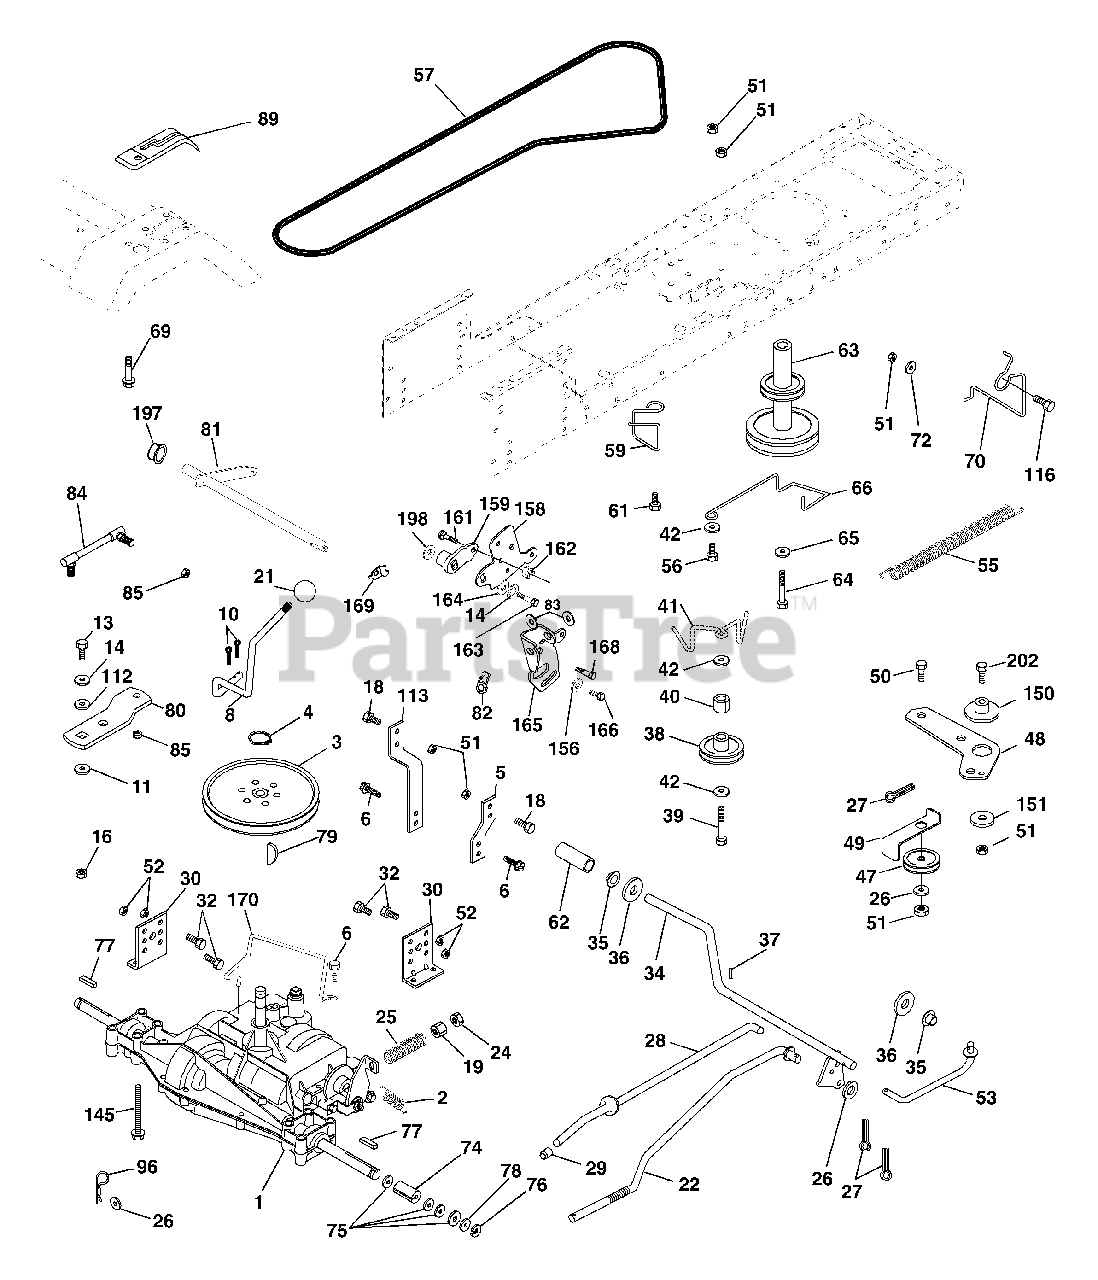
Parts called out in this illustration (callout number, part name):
2	Spring Return Brake T/a Zinc
3	Pulley Transaxle 18" tires
4	Ring Retainer # 5100-62
5	Strap Torque 30 Degrees
6	Screw 5/16-18 X 3/4
8	Rod Shift Fender Adjust Lt
10	Pin Cotter 1/8 X 1 Cad
11	Washer Plate Shf 388 Sq Hole
13	Bolt 1/4-28 Unf Gr 8 W/Patch
14	Washer Lock Hvy Helical
16	Nut Lock Hex w/ins 5/16-18
18	Bolt, Fin Hex 3/8-16 UNC x 1 Gr. 5
19	Nut Lock 3/8-16 Unc
21	Knob
22	Rod Brake Blk Zinc 26 840
24	Nut Hex Jam 3/8-16 Unc
25	Spring Rod Brake 2 00 Zinc
26	Washer 13/32 X 13/16 X 16 Ga
27	Pin Cotter 1/8 X 3/4 Cad
28	Rod Brake Parking LT/YT
29	Cap Brake Parking
30	Bracket Mtg Transaxle
32	Bolt Hex Hd 5/16-18unc X 3/4
34	Shaft Asm Pedal Foot
35	Bearing Nylon Blk 629 Id
36	Washer 21/32 X 1 X 16 Ga
37	Pin Roll 3/16 X 1"
38	Pulley Idler Flat
39	Bolt Fin Hex 3/8-16unc X 2-3/4
40	Spacer Split 395 X 59 Bzp
41	Keeper Belt Flat Idler
42	Washer 13/32 X 13/16 X 12 Ga
47	Pulley Idler V Groove Plastic
48	Bellcrank Asm
49	Retainer Belt Style Spring
50	Bolt Hex Hd 3/8-16unc X 1-1/2
51	Nut Crownlock 3/8-16 Unc
52	Nut Crownlock 5/16-18 Unc
53	Link Clutch
55	Spring Return Clutch 6 75
56	Bolt Fin Hx 3/8-16 X 1/4
57	V-Belt Ground Drive 95 25
59	Keeper Belt Span Ctr
61	Screw 3/8-16x.75
62	Cover Pedal Blk Round
63	Engine Pulley LT/YT
64	Bolt Hex
65	Washer Lock Hvy Hlcl Spr 7/16
66	Keeper Belt Engine Foolproof
69	Screw Hex wsh Hi Lo 1/4 x 1/2 unc
70	Guide Belt Mower Drive RH
72	Washer 13/32 X 1-1/4 X 12 Ga
74	Spacer Axle
75	Washer 25/32 X 1 1/4 X 16 Ga
76	E-ring #5133-75
77	Key Square 2 0 X 1845/ 1865
78	Washer 25/32 X 1-5/8 X 16 Ga
79	Key Woodruff #9 3/16 x 3/4
80	Arm Shift
81	Shaft Asm Cross Tapered PMST/20
82	Spring Torsion T/a
83	Washer 17/32 X 3/4 X 16 Ga
84	Link Transaxle PMST/20" Zinc
85	Nut Lock Center 1/4-28 FNTHD
89	Console Shift STLT
96	Retainer Spring 1"
112	Washer 9/32 x 3/4 x 10 Ga.
113	Strap Torque LT
116	Bolt Rdhd Sq Neck 3/8-16 x 1.25
145	Bolt Hex FLGHD 5/16-18 Gr. 5
150	Bushing Bellcrank
151	Washer 13/32 x 2 x 10
156	Washer Srrted 5/16ID x 1.125
158	Bracket Shift Mount
159	Hub Tapered Flange Shift Lt
161	Bolt Rdhd Sqnk 1/4-20 x 3/4 Gr
162	Nut Crownlock 1/4-20 Unc
163	Bolt Hex Fin 1/4-20 Unc x 1 Gr 5
164	Washer 5/8 x .281 x 10 Ga
165	Bracket Pivot Lever
166	Screw 5/16-18 x 5/8
168	Bolt Shoulder 5/16-18 x .561
169	Plate Fastening
170	Keeper Belt Transaxle Pmst/Dana
197	Nyliner Snap-In
198	Washer Nyliner
202	Bolt Carr Sh 3/8-16 x 1-1/2 Gr. 5
